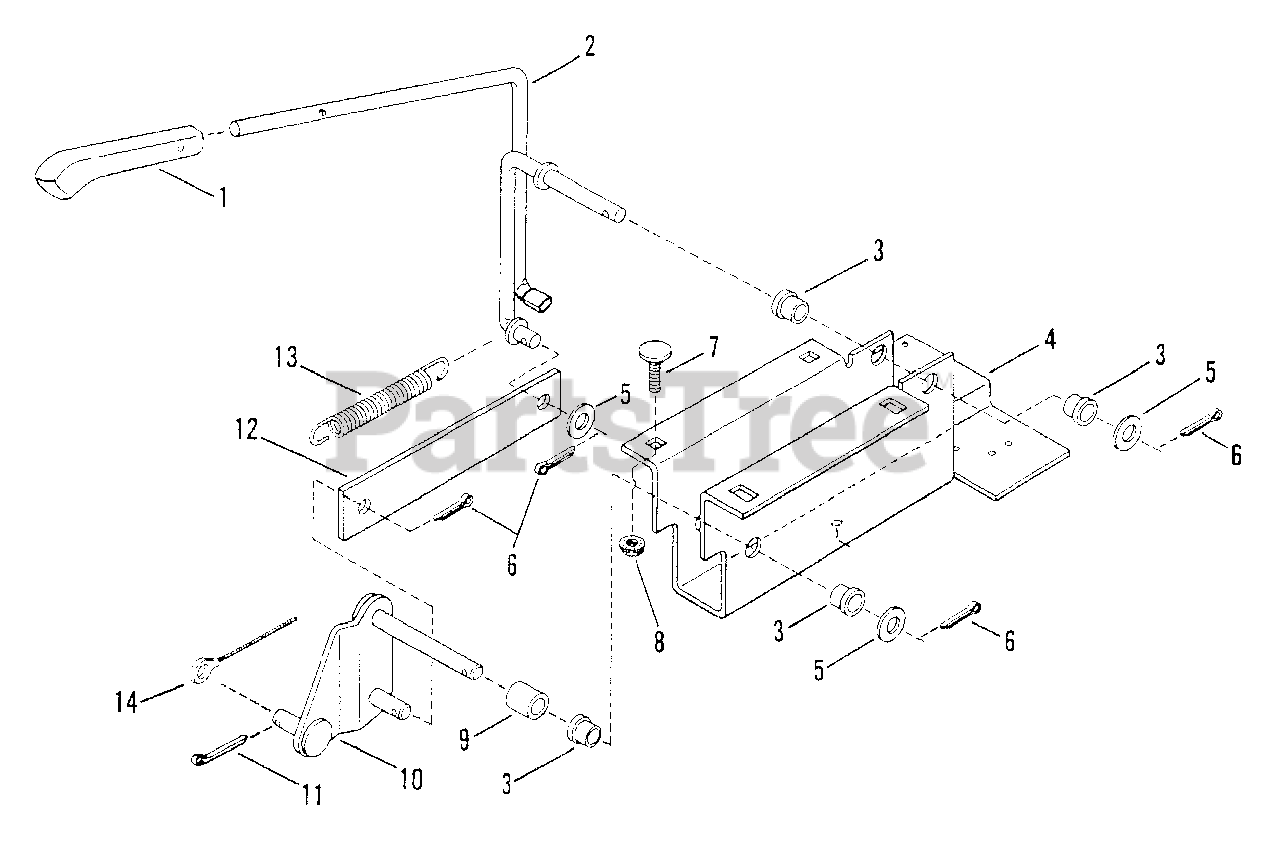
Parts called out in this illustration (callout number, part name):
1	KNOB, Handle
3	BUSHING
4	BRACKET, Handle
5	WASHER 3/8 Flat
6	PIN, 3/32 x 3/4" Cotter
7	BOLT, 1/4-20 x 5/8" Flat Head Carriage
8	NUT, 1/4-20 Hex Flange Lock
9	SPACER
10	ASSEMBLY, Pivot Arm
11	PIN, 3/32 x 1" Cotter
13	SPRING, Return
14	CABLE, Blade (33" Models) 28.5"
